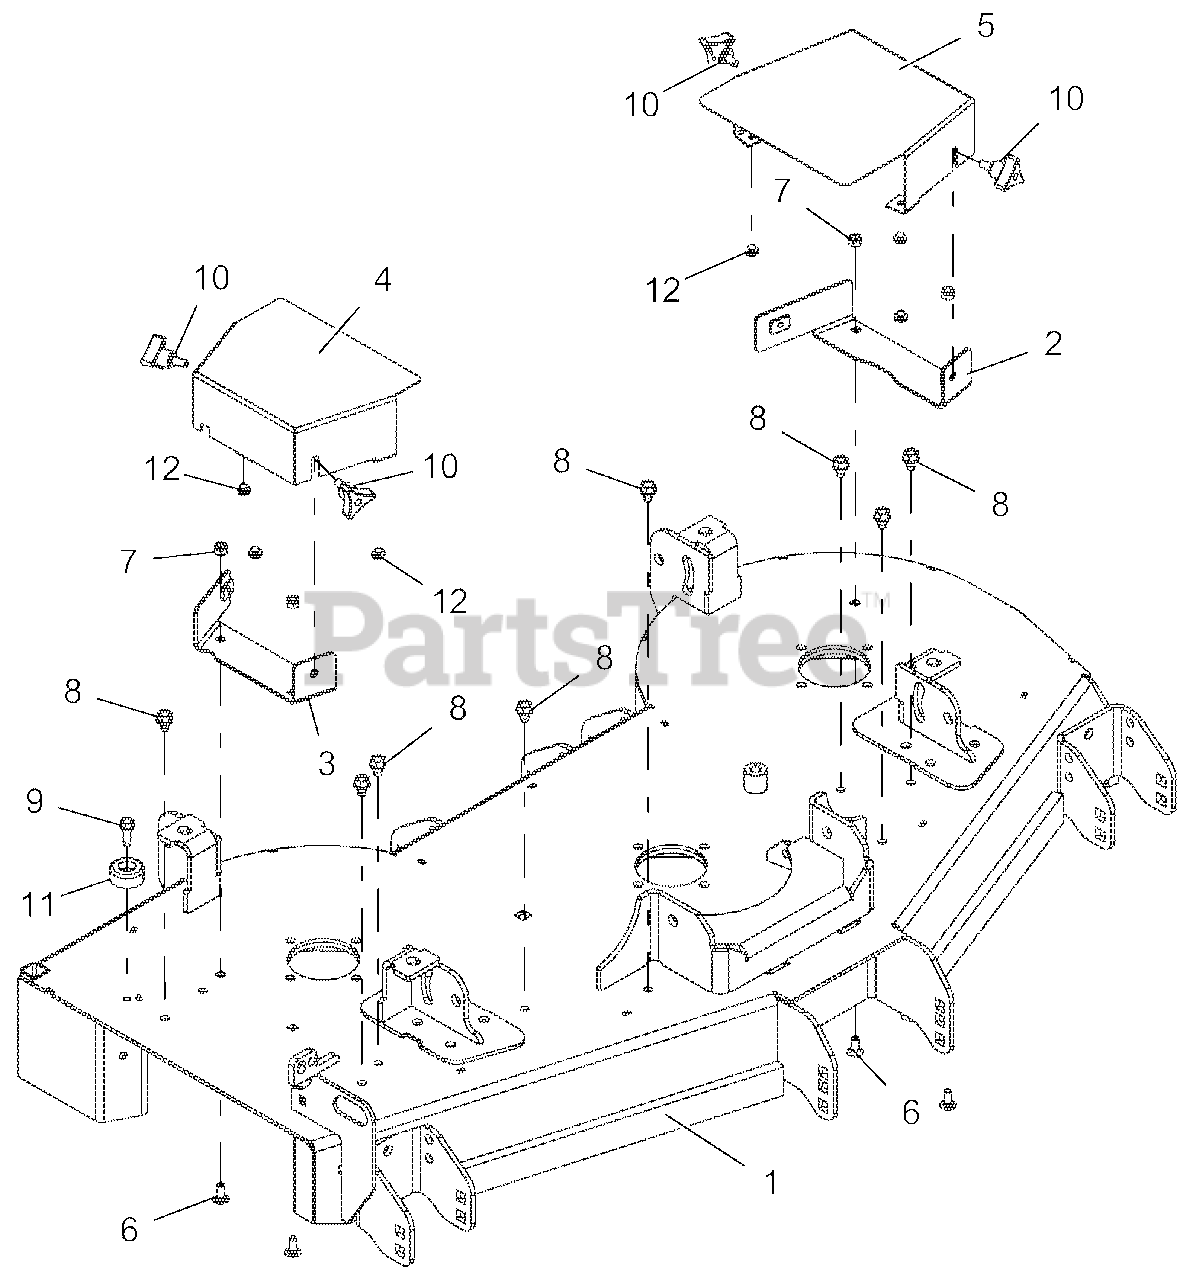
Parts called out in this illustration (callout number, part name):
1	KIT, 48 IN PROSTANCE MOWER DECK W/SAFETY DECALS-RED
2	WLDMT, RH BRKT BELT GUARD MOUNTING-RED
3	WLDMT, LH BRKT BELT GUARD MOUNTING-RED
4	GUARD, RH DECK BELT
5	GUARD, LH DECK BELT-RED
6	BLT-RDHDSQNK .31-18X.75 G5 YWZC
7	NUT-LK-NYL .312-18 YWZC
8	SCR-TAP .38-16X.50 HWH TR YWZ
9	SCR-TAP .31-18X1.00 HWH TR YZ
10	KNOB, WING STUD .312-18X.75
11	BUMPER, RECESSED 1.50 X .63 W/.31 HOLE
12	BUMPER GROMMET .125 X .25 REV
